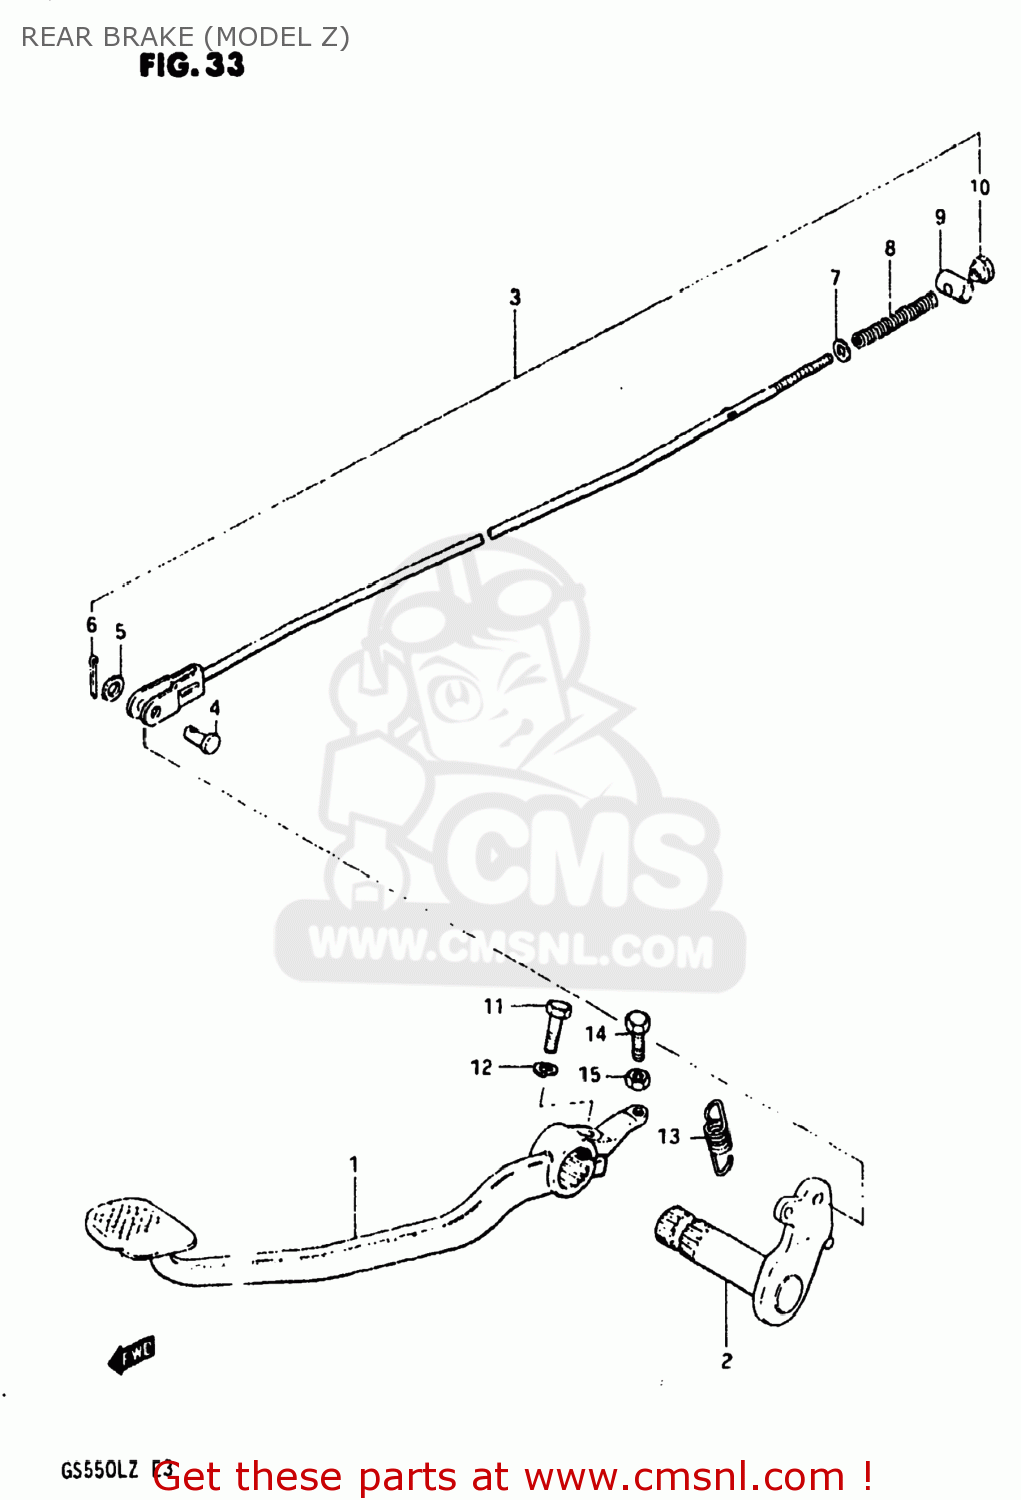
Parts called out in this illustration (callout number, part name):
1	PEDAL,BRAKE
2	ARM,BRAKE PEDAL
3	ROD ASSEMBLY,REAR BRAKE
4	PIN(L:13.5)
5	WASHER
6	PIN 20X20
7	WASHER
8	SPRING
9	PIN
10	NUT
11	BOLT
12	LOCK WASHER
13	SPRING
14	BOLT
15	NUT
